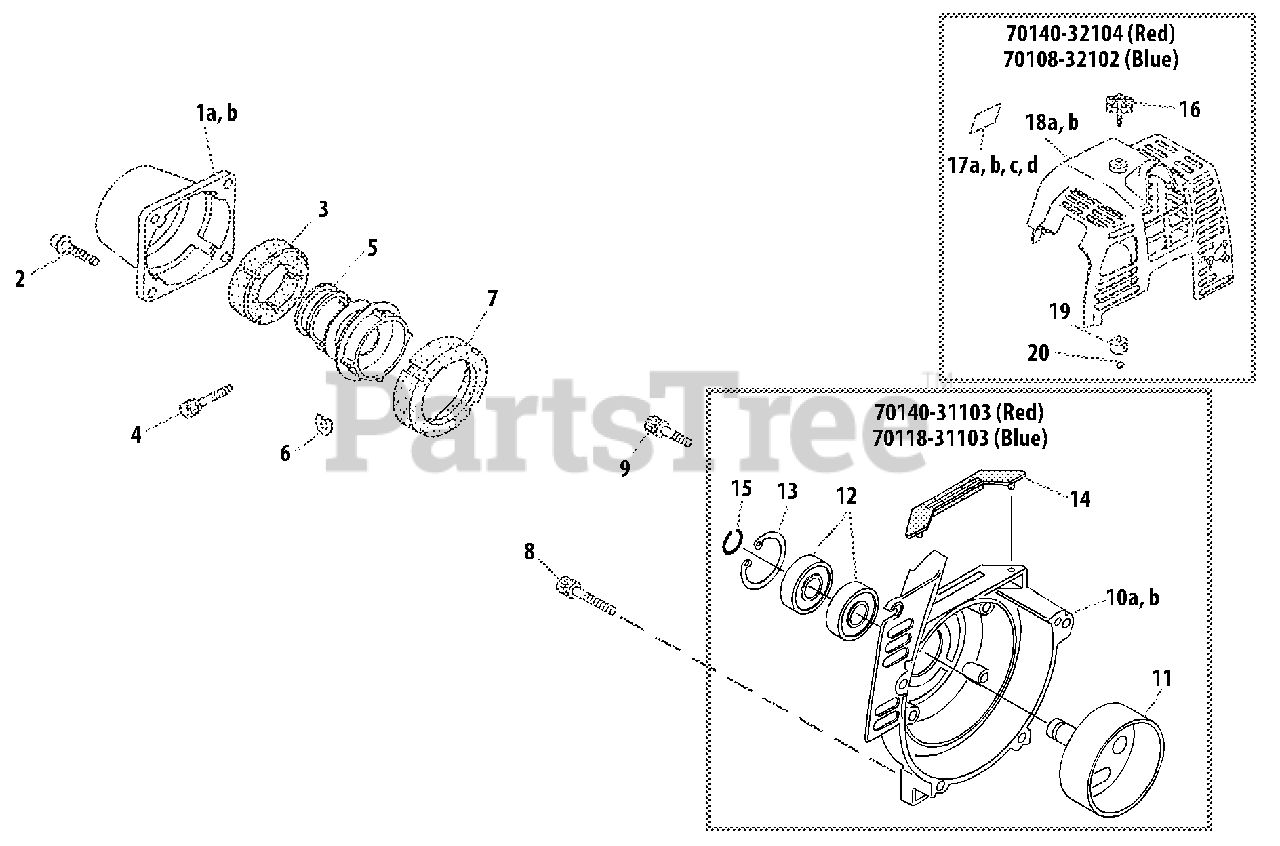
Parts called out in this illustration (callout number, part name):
1	COVER, AV CUSHION (RED)
1	COVER, AV CUSHION (BLUE)
2	BOLT M5×16
3	CUSHION, FRONT
4	BOLT M5×25
5	JOINT
6	D-WASHER
7	HOLDER, REAR CUSHION
8	BOLT M5×16
9	BOLT M5×35
10	COVER, FAN
10	CASE, FAN
11	DRUM, CLUTCH
12	BEARING, BALL 6000ZZ
13	RING, SNAP Ø26
14	CUSHION
15	RING, SNAP WR10
16	THUMBSCREW
17	LABEL
17	LABEL - MODEL C230
17	LABEL, TRADE
18	COVER, ENGINE
19	INSULATOR 5 MM
20	CLIP
70108-32102	ENGINE COVER KIT - BLUE
70118-31103	FAN CASE ASSY
70140-31103	COVER ASSY, FAN
70140-32104	ENGINE COVER KIT - RED
